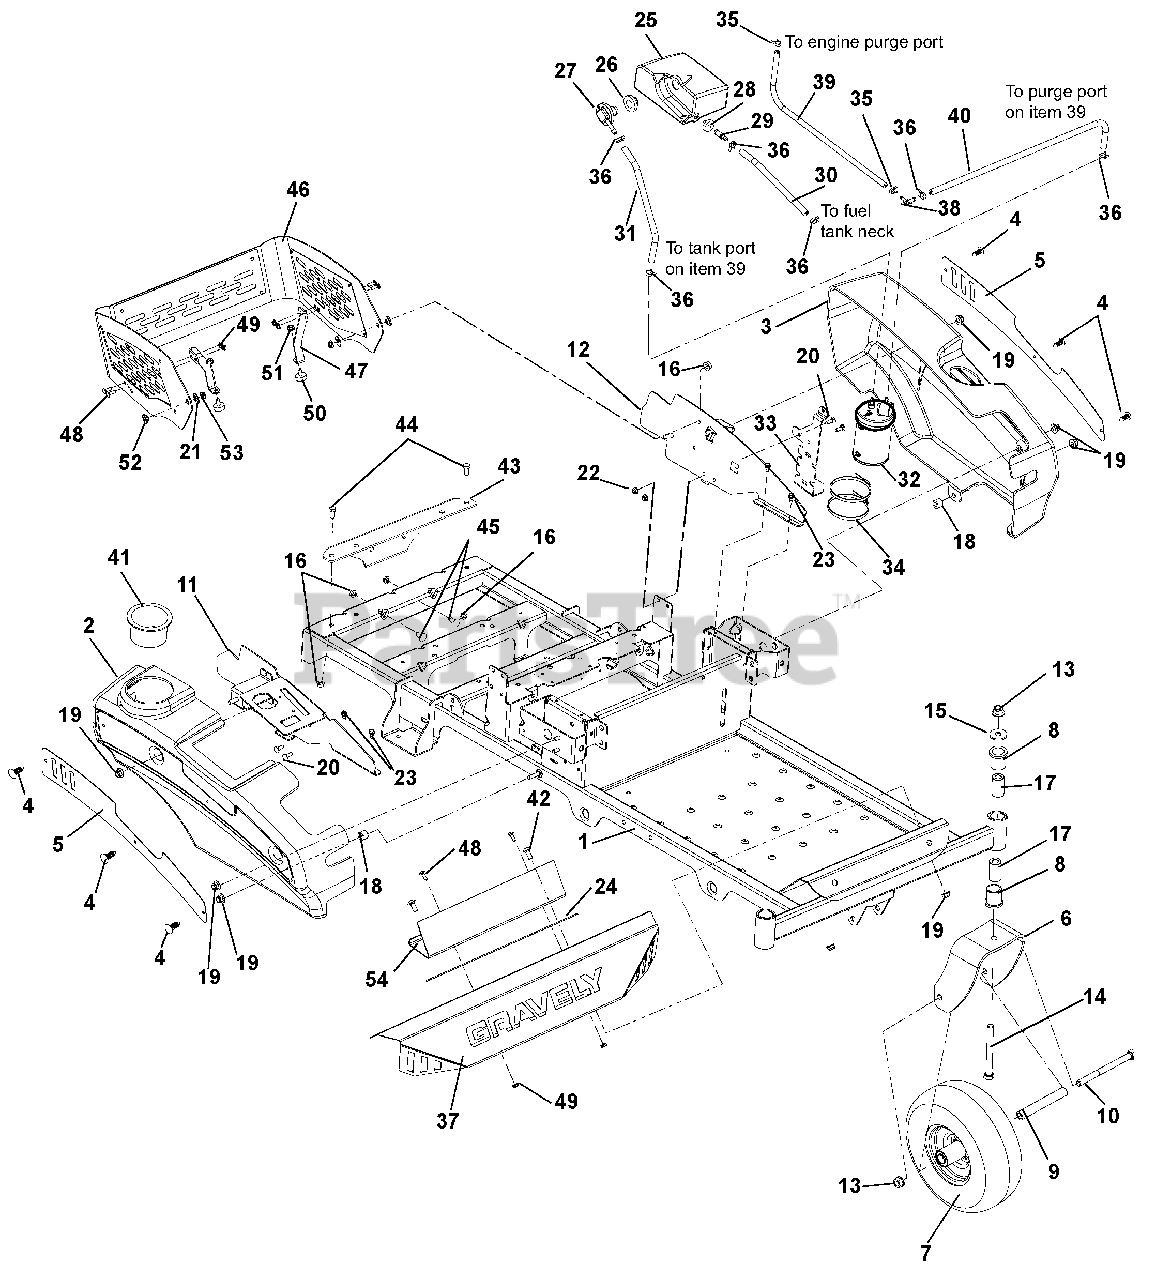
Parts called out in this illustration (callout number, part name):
1	Weldment, Frame
2	Fender, Right Hand
3	Fender, Left Hand
4	Rivet, Nylon
5	Plate, Fender
6	Fork, Caster
7	Wheel/Tire Assembly, 11 x 4-5
8	Bushing, Flange 1.00 x 1.25 x 1.50 x 1.50
9	Spacer, Wheel
10	Bolt, Hex .50-13 x 6.50
11	Weldment, Fender Mount Right Hand
12	Weldment, Fender Mount Left Hand
13	Nut, Locking Top Flange .50-13
14	Bolt, Hex .50-13 x 5.00
15	Washer, Flat Steel .511 x 1.441 x .125
16	Nut, Locking Top Flange .38-16
17	Spacer, Caster
18	Bushing, Sleeve .391 x .688 x .52
19	Nut, .31-18 Nyloc Flange
20	Bolt, Round Head Square Neck .25-20 x .75
21	Washer, Flat Nylon .52 x 1.00 x .08
22	Nut, .25-20 Nyloc Flange
23	Screw, Tapping .25-20 x .50 Hex Washer Head Thread
24	Grip, Adhesive (1" x 16" BLK)
25	Tank, ZT/Waw Fuel Exp.
26	Grommet, Remote Vent Nitrile
27	Vent, Roll-Over (.25" ID Hose)
28	Bushing, Flange .375 x 1.062 x .625 R
29	Fitting, Straight Fuel
30	Hose, .25 Low-Perm Bulk Gas
31	Hose, .25 Low-Perm Bulk Gas
32	Carbon Canister, 300CC
33	Bracket, Mount, Canister BBZ
34	Plastic Tie Strap Large
35	Clamp, Hose Spring .188
36	Clamp, Hose Wire .490/.510 x .116
37	Foot Rest
38	Fitting, 3/16 x 1/4 90 Deg Vac
39	Hose, .188 Low Perm Bulk (915168)
40	Hose, .25 Low Perm Bulk Gas (915168)
41	Cupholder
42	Bolt, Round Head Square Neck .31-18 x .75
43	Plate, BBZ Hitch Kit Plate (915170)
44	Bolt, Hex .38-16 x .75 (915170)
45	Bolt, Round Head Square Neck .31-16 x .75 (915170)
46	Assembly, Engine Wrap
47	Bracket, Engine Wrap Foot
48	Bolt, Round Head Square Neck .25-20 x .50
49	Nut, Center Lock Flange .25-20
50	Bumper, Rubber
51	Nut, Serrated Flange .31-18
52	Bushing, Flange .325 x .499 x .3 x .875
53	Nut, Center Lock Flange .31-18
54	Plate, Back Foot Rest
